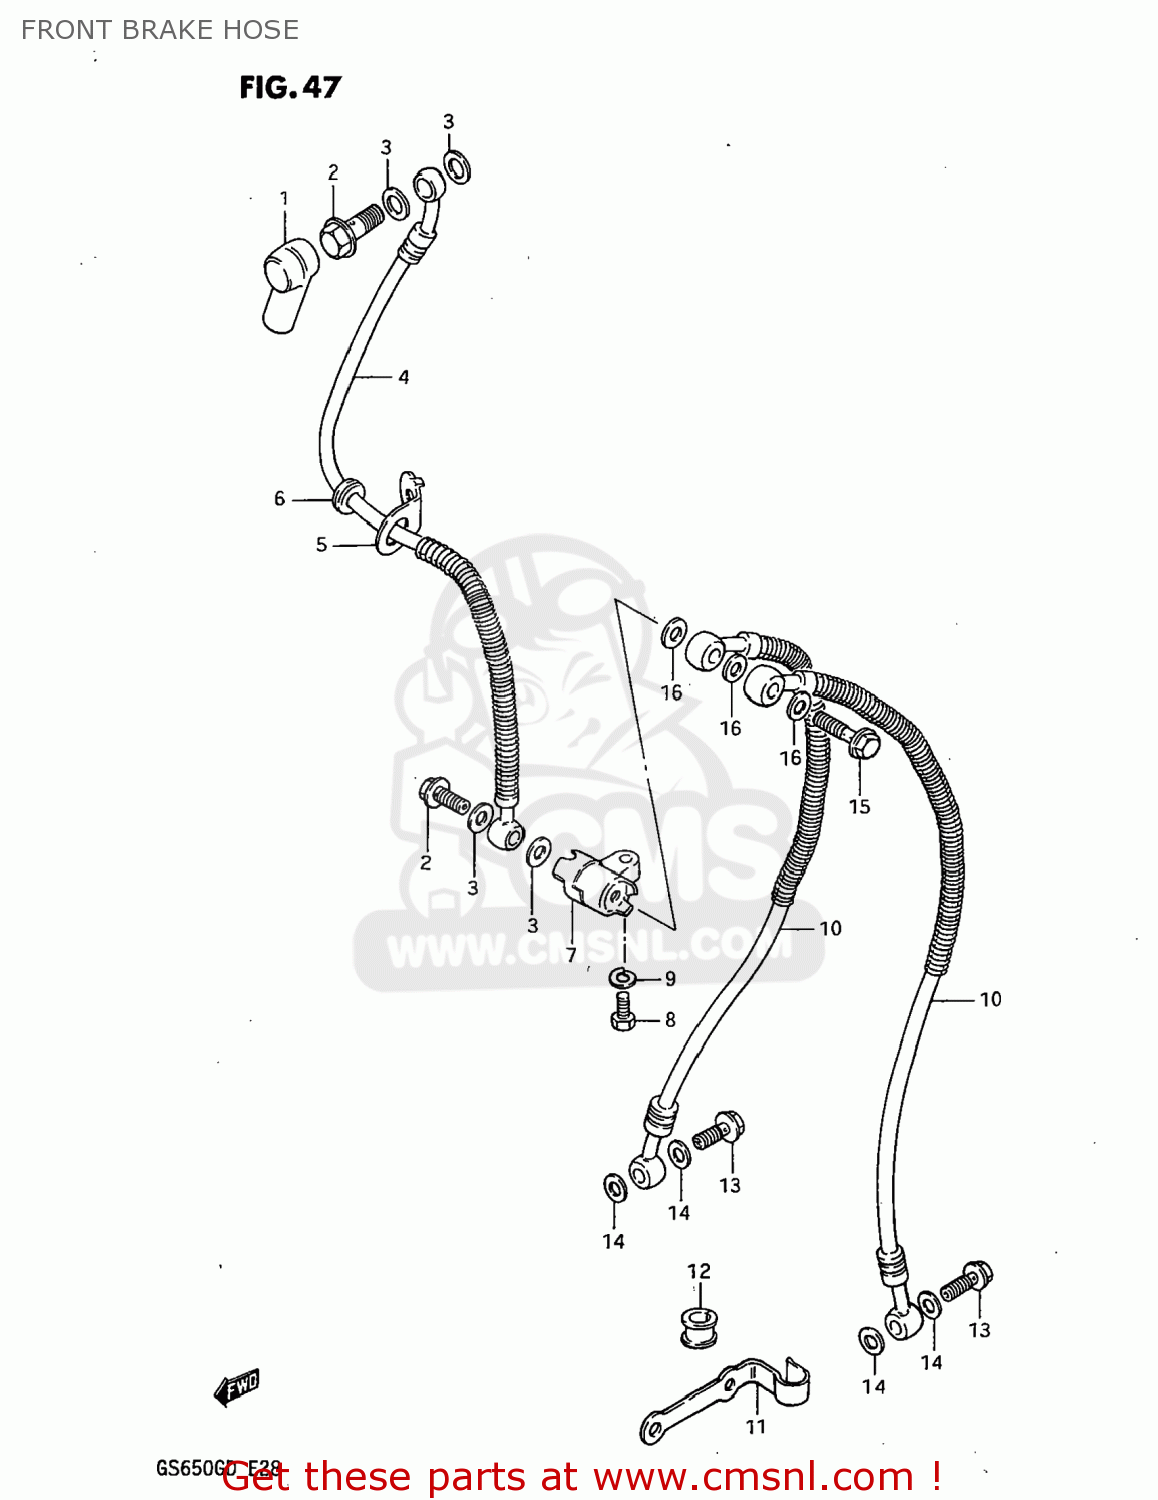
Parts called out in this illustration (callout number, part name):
1	BOOT,MASTER CYLINDER
2	BOLT,UNION
3	WASHER
4	HOSE,FRONT BRAKE
5	GUIDE,BRAKE HOSE NO.1
6	GROMMET
7	JOINT,BRAKE HOSE
8	BOLT
9	LOCK WASHER
10	HOSE,FRONT BRAKE
11	GUIDE,BRAKE HOSE NO.2
12	BUSH,BRAKE HOSE GUIDE,NO.2
13	BOLT,UNION
14	WASHER
15	BOLT,UNION
16	WASHER
